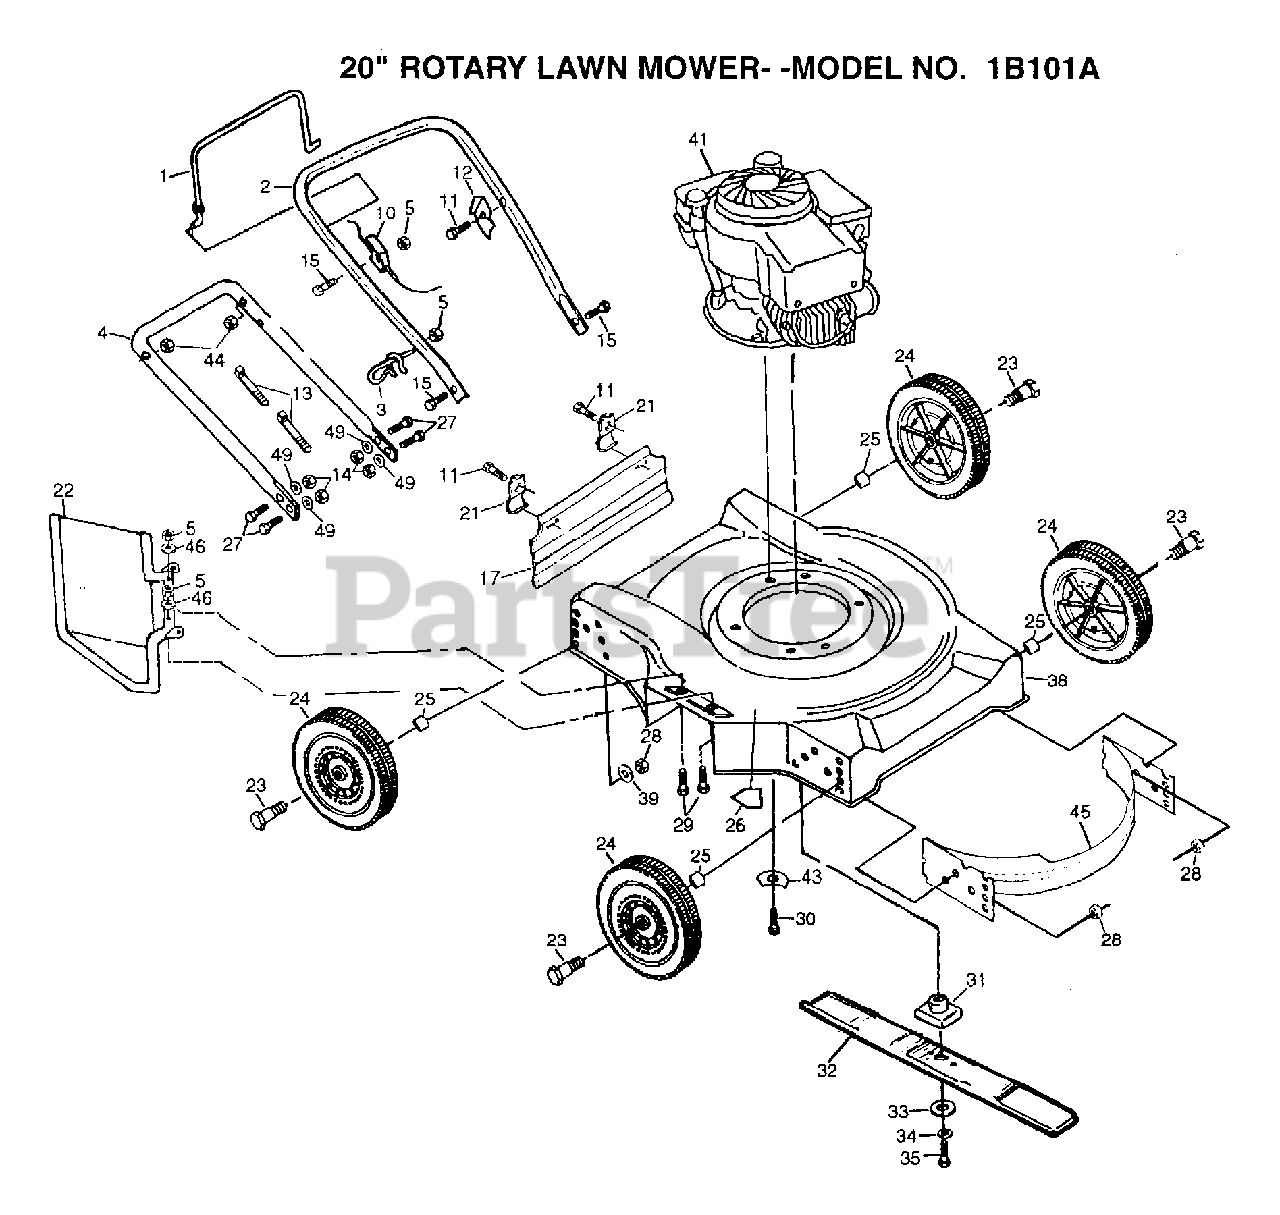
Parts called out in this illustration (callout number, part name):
1	CONTROL BAR PM
2	UPPER HANDLE
3	ROPE GUIDE
4	HANDLE LWR PM
10	CABLE.CONT.ENG
11	TAPPING SCREW
12	"BRKT,UPSTOP"
14	LOCKNUT
15	BOLT 1/4-20-1 1/2
21	"BRKT,DEFL PM"
22	"GRD,DISCHARGE"
23	AXLE BOLT
24	WHEEL ASSY
26	DECAL HYT
28	LOCKNUT PM
29	BOLT LT
30	SCREW
31	BLADE ADAPTOR
32	BLADE.STAND.20INC
33	"WASHER,HARDEN"
34	LOCKWASHER
35	SCREW
49	STEEL WASHER
